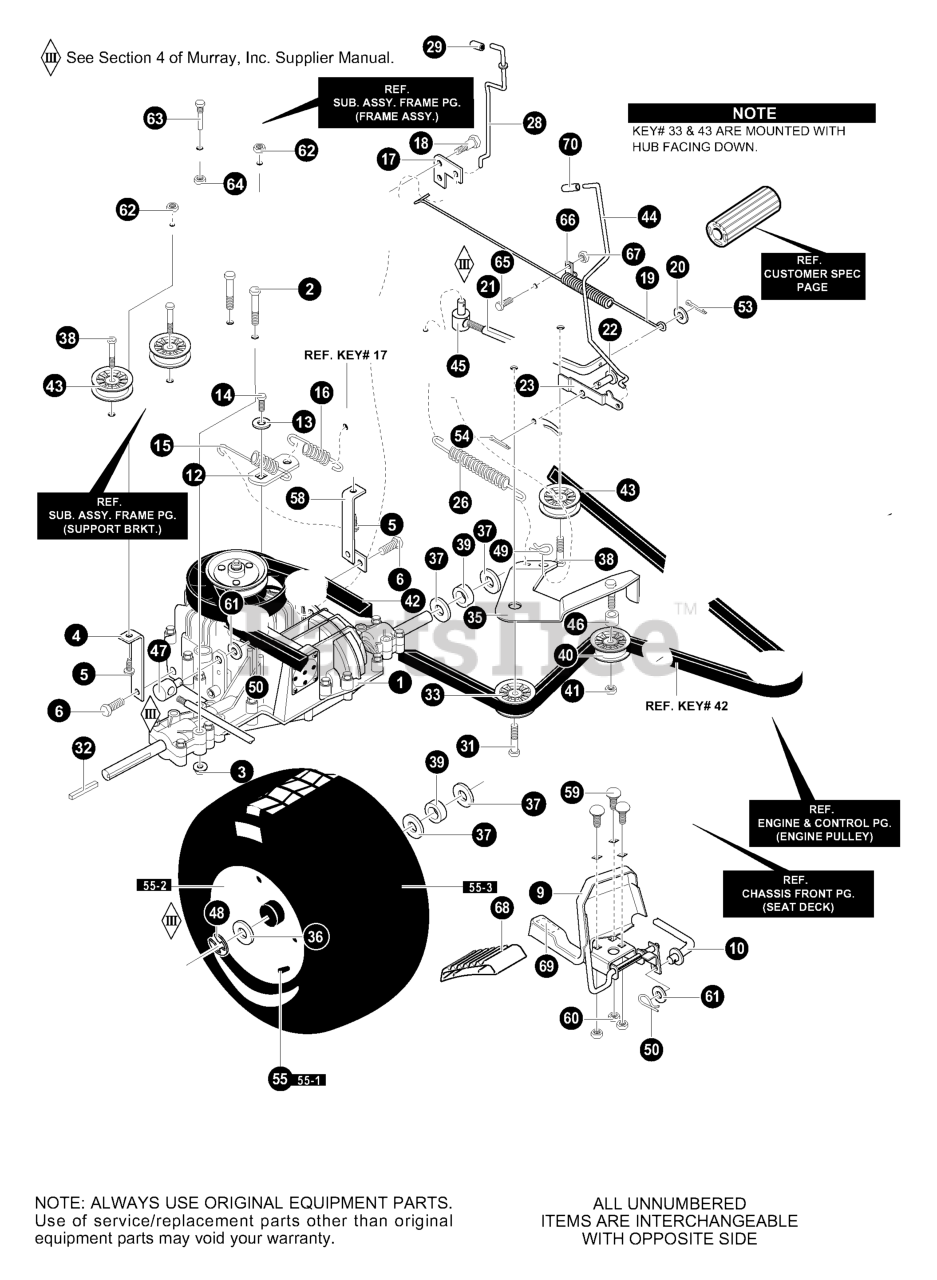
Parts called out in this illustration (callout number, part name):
1	TRANSAXLE HYDRO VST205-025BM **
2	SCREW, 5/16-18 x 2.50
3	NUT, 5/16-18 WDFLLK
4	BRACKET, STABILIZER HYDRO
5	SCREW, 5/16-18 x 1.00
6	SCREW, 5/16-18 x 0.75 WAHHTAP
9	PEDAL ASSY HYDRO
10	ROD, FOOT CONTROL
12	BRACKET, SHIFT
13	WASHER, .750X.250 SP-TRANSAXLE
14	SCREW, 1/4-28X.750
15	SPRING - TRANSAXLE DISCONNECT
16	SPRING, 3/8 ODX2.18X.055 TENSION
17	BRACKET, DISCONNECT LEVER
18	BOLT, .437X.136HHSHTAP 5/16-18
19	SPRING, BRAKE
20	WASHER, FLAT.328X1.06X.062
21	ROD, CLUTCH
22	PIN, CLEVIS
23	LATCH, PARK BRAKE
26	SPRING, TENSION
28	ROD, DISCONNECT CONTROL
29	GRIP, HYDRO DISCONNECT
31	SCREW, 3/8-16 x 1.25
32	KEY, SQUARE
33	PULLEY, IDLER
35	ASSY, IDLER ARM TRACTION
36	WASHER, FLAT .765 x 1.81 x .059
37	WASHER, FLAT .755ID
38	SCREW, 3/8-16 x 1.25
39	SPACER, .87X1.78
40	PULLEY, IDLER 2.75 DIA
41	NUT, 3/8-16 HWDFLLK
42	BELT, V 4L 112.75
43	PULLEY, IDLER V4L3.00X.710
44	PARK BRAKE CONTROL ROD
45	NUT, 5/16-18X3/8 ADJUSTING
46	SPACER 1/2 TO 17MM
47	ADJUSTING NUT 1/2-13UNC
48	E-RING .574IDX.050/.75
49	PIN, HAIR .072DIAX1.13LG
50	PIN, HAIR
53	PIN, COTTER .094 DIAX.75LG
54	PIN, COTTER .094 DIAX.75LG
55	TIRE & RIM
55-1	VALVE STEM
55-2	RIM, CARL
55-3	TIRE, 20X8X8
58	WELD BRACKET STABILIZER LH
59	BOLT, 5/16-18X.75 CARR.
60	NUT, 5/16-18 HEXWDFLLK WHIZ
61	WASHER, FLAT .515X.88X.064
62	NUT, 1/4-20 HEXNYL
63	SCREW GUIDE
64	NUT, 5/16-18 HEXWDFLLK WHIZ
65	SCREW, 1/4-20 X.50
66	RETAINER, WIRE .31IDX.62X.03
67	NUT, 1/4-20 WDFLWHIZ-LK
68	PEDAL, TOE SANDPAPER
69	PAD, TOE SANDPAPER
70	CAP, DUMP VALVE ROD
